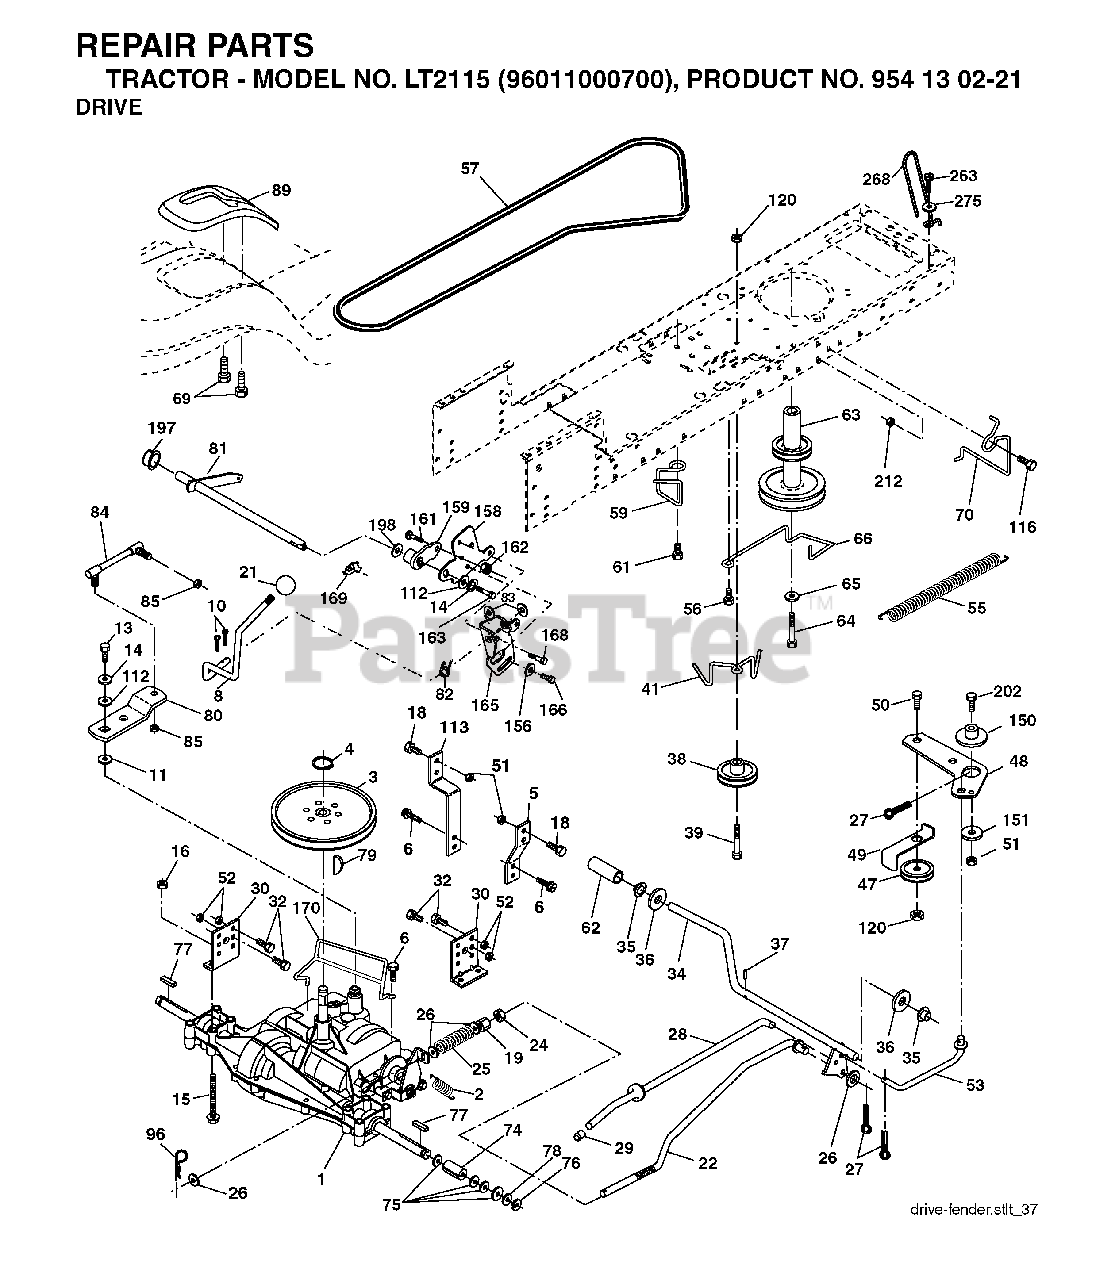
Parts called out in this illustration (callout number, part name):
8	ROD.SHIFT.FENDER.ADJ.STLT
10	PIN COTTER
14	LOCKWASHER
15	BOLT HEX 5/16-18 GR 5
16	NUT.71038.31-18.HEX.NYLOCK
19	NUT
21	KNOB.DUCKHEAD.1/2
22	ROD BRAKE HYDRO
24	NUT
25	SPRING ROD LT
27	COTTER PIN
28	ROD, PARKING BRAKE
29	PLUNGER CAP
30	BRKT, MOUNT TRNSAXLE
32	BOLT
34	SHAFT, FOOT PEDAL
35	BEARING.NYLON
36	WASHER LT
37	DRIVE PIN
38	PULLEY IDLER COMPOSITE
41	KEEPER, BELT IDLER
47	IDLER PULLEY
48	BELLCRANK, CLUTCH
49	RETAIN BELT
50	BOLT.3/8-16X1.50
51	LOCKNUT
52	LOCKNUT
53	LINK, CLUTCH LT
55	SPRING, RETURN LT
56	SCREW.3/8-16
57	DRIVE BELT, LTH & YTH TRACTORS
59	KEEPER, BELT CENTER
61	SCREW 3/8-16X.875
62	PEDAL COVER T
64	BOLT HEX 7/16-20X4-1/4"
65	LOCKWASHER
66	KEEPER BELT ENGINE
69	SCREW.HI-LO.CONSOLE
71	STRAP TORQUE LH HYDRO
73	STRAP TORQUE RH HYDRO
74	SPACER AXLE
76	E-RING LT
77	SQUARE KEY
81	SHAFT ASM CROSS TAPERED
82	SHIFT SPRING
83	WASHER
89	CONSOLE SHIFT STLT
95	CONTROL ASM. BYPASS HYDRO
96	RETAINER M
103	NUT.HEX.1/2-20
112	WASHER LT
116	BOLT D
120	NUT LOCK FLG 3/8-16 UNC
150	SPACER, RETAINER
151	WASHER 12/32X2X10GA
156	WASHER.SRRTD.5/16
158	BRACKET
159	HUB.SHIFT
161	BOLT
162	NUT.CROWNLOCK.1/4
165	RP BRACKET
168	BOLT.SHOULDER.5/16-18X
169	PLATE.FASTENING.CROSS.SHAFT
197	NYLINER SNAP 5/8" ID
198	WASHER.NYL.7/8IDX.105"HYD CR
199	BOLT SHOULDER 5/16-18 UNC
200	BOLT
202	BOLT
205	WASHER
212	NUT
263	SCREW, 3/8-16X3/4
275	WASHER
